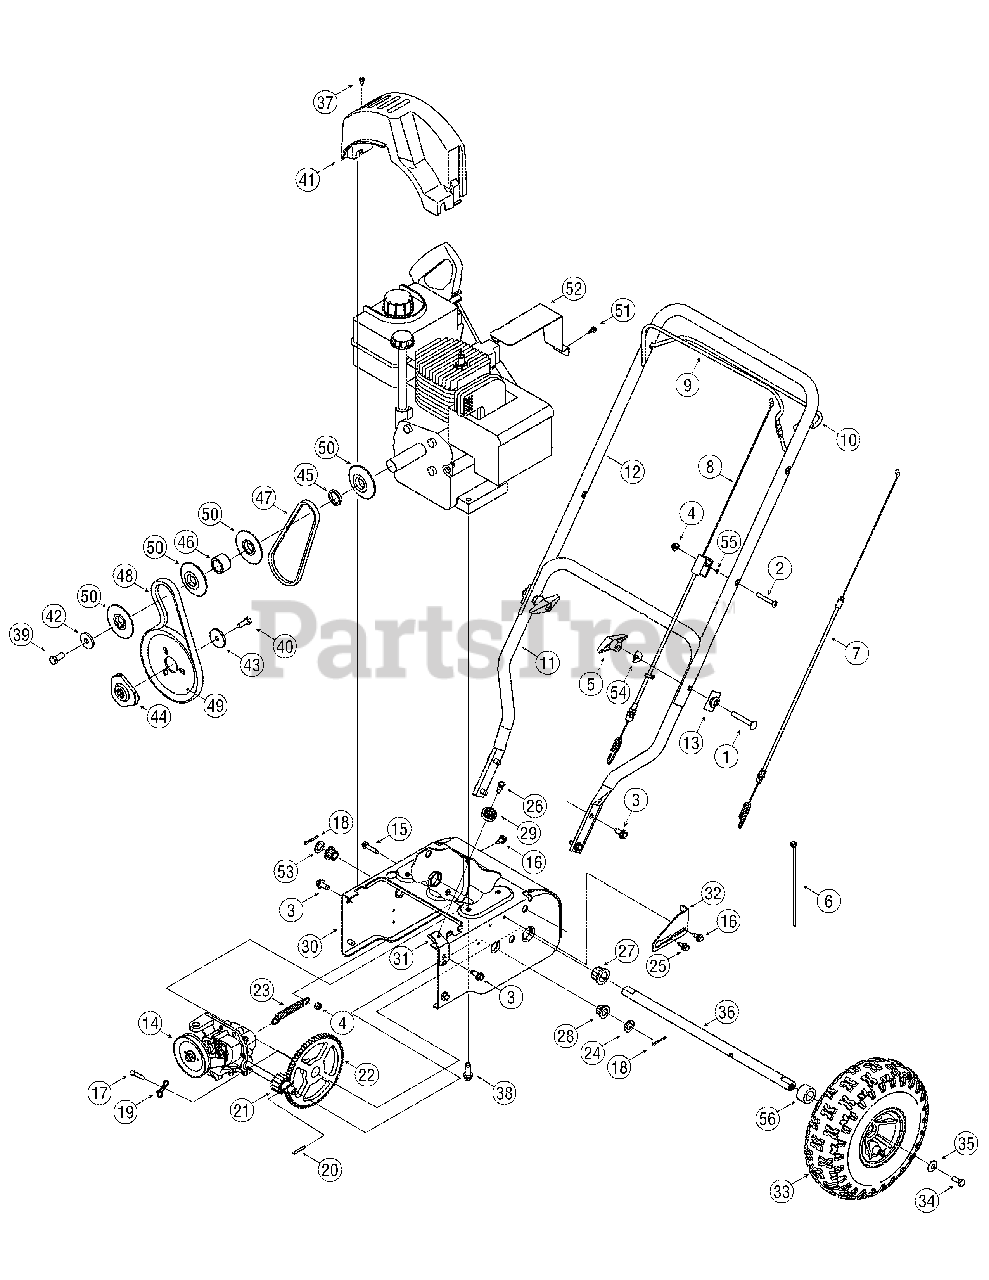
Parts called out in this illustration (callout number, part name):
1	Carriage Screw 5/16-18 x 2.25
2	Mach. Screw 1/4-20 x 1.825
3	Screw 5/16-18 x .75
4	Flange Lock Nut 1/4-20
5	Wing Knob 5/16-18
6	Cable Tie
7	Drive Cable
8	Auger Cable
8	Fitting, Dual Cable
9	Auger Control
10	Drive Control
13	Handle Tab
14	Transmission Assembly
15	TT Screw 1/4-20 x 1.25
16	Screw 1/4-20 x .625
17	Clevis Pin
18	Cotter Pin 1/8 x 1.0
19	Bow Tie Cotter Pin 72
20	Roll Pin
21	Pinion 14T
22	Gear 70T
23	Extension Spring
24	Flat Washer
25	Shoulder Screw 1/4-20
26	Shoulder Screw 1/4-28
27	Hex Flange Bearing
28	Hex Flange Bearing
29	Cable Roller
31	Auger Cable Bracket
33	Wheel Assy Snow Hog Gray
34	Lock Bolt 5/16-24 x .75
35	Bell Washer .34 x .872 x .06
37	Hex Screw #10-16 x .500
38	TT Sems Screw 3/8-16 x 1.0
39	Hex Bolt 3/8-24 x .875
40	Lock Bolt 5/16-24 x .875
41	Belt Cover
42	Flat Washer .406 ID x 1.25 OD
43	Flat Washer .34 ID x 1.50 OD
44	Pulley: Adapter .75 Dia.
45	Spacer .876 x 1.25 x .19
46	Spacer .876 x 1.25 x .86
47	V-Belt 3/8 x 21.108 Lg.
48	V-Belt 3/8 x 26.680 Lg.
49	Auger Pulley
50	Pulley Half
51	Screw #10-16 x .500
52	Heat Shield
53	Flat Washer .53 x .93 x .05
54	Saddle Washer
55	Spacer
